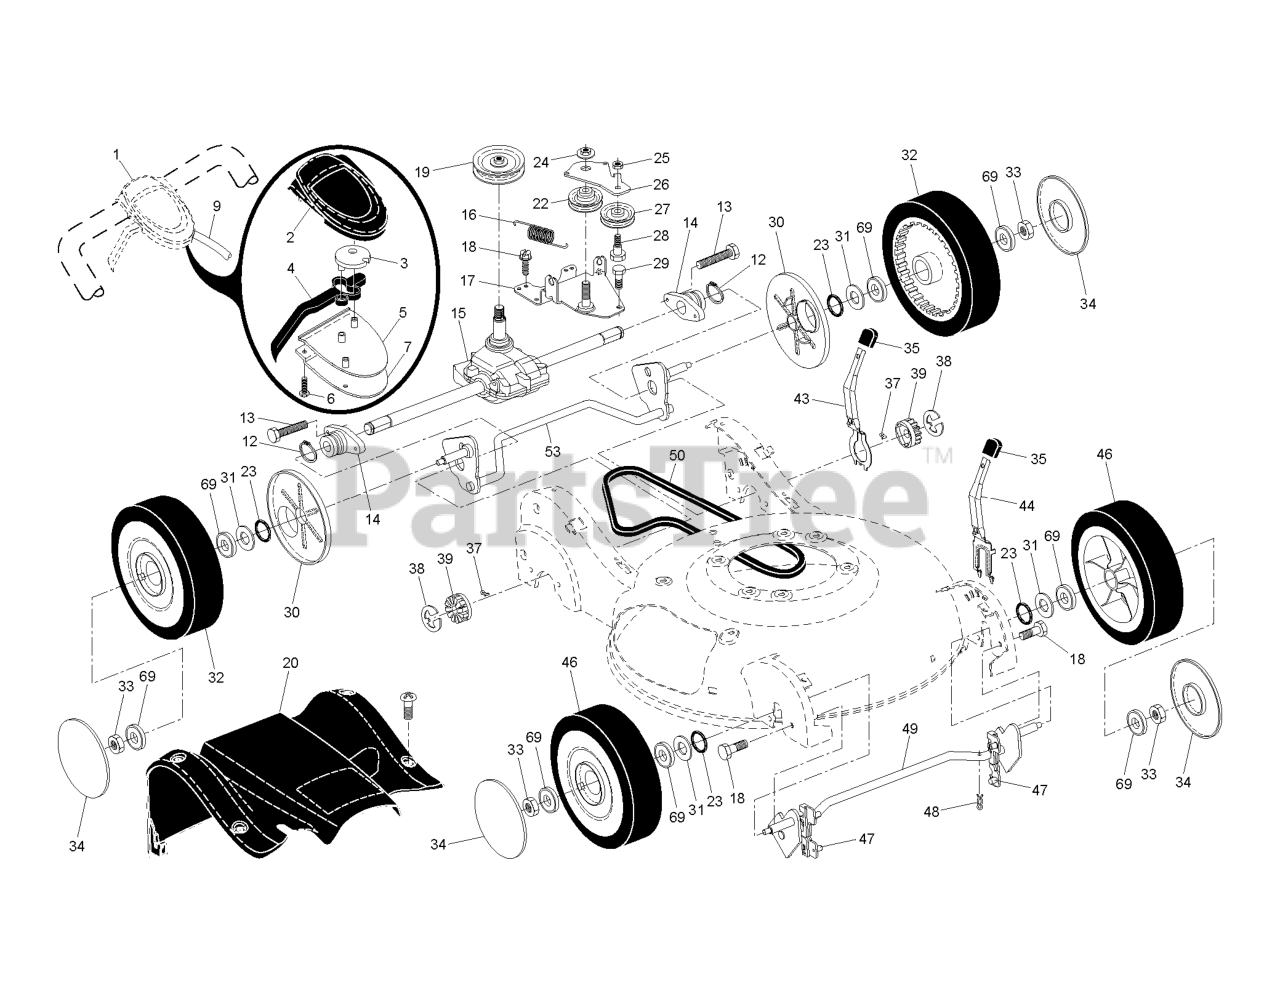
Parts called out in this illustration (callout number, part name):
1	Drive Control Assembly, Complete
2	COVER TOP AUTO WALK CONTROL
3	PULLEY.CAM.DRIVE.CONTROL.HV
4	LEVER.BLACK
5	COVER BOTTOM AUTO WLK CONTROL
6	SCREW, PHILLIPS HEAD 10 X 5/8
7	BRACKET.DRIVE.CONTROL.MOUNT.BL
9	ASM.CABLE.
12	RETAINING RING (2 2)(3 2)
13	SCREW.1/4-20X21/4.HEX.
14	BEARING / AXLE SUPPORT
15	TRANSMISSION.21.HV.RWGD.AW/EZ
17	BRACKET, GEAR CASE / DRIVE
19	RP PULLEY.DRIVE.EZ
20	COVER.DR.ASM.408006X418.CE
22	PULLEY.IDLER.V-BELT
23	O-RING..070X.487.NEOPRENE
24	NUT.HEX.FLANGE.3/8-16.LOCKNUT
25	NUT.CENTERLOCK.5/16-
26	ARM.IDLER.BZP
27	IDLER PULLEY
28	SHOULDER BOLT
29	SCREW 14-20 X 5/8
30	DUST COVER, WHEEL
31	WASHER.FLAT.1/2
32	WHEEL.9X2.25.LP.TIGER.BLACK
33	NUT.HEX.FLANGE.3/8-16.LO(3 2)
34	HUBCAP.WHEEL.5.SPOKE.SILVER
35	KNOB.SELECTOR.SPRING.BLACK(3 2
37	PAWL, DRIVE
38	E-RING 7/16 RE
39	PINION.14.TEETH.FGD
43	LEVER, SELECTOR, HEIGHT, REAR
44	LEVER, SELECTOR, HEIGHT, FRONT
46	WHEEL.9X2.25.LP.TIGER.BLK
47	BUSHING.FRONT.TORQUE.SHAFT
48	SPRING RETAINER
49	SHAFT FRONT
50	BELT, DRIVE
53	SHAFT.ASM.REAR.TORQUE.HV.BZP
69	BEARING.8".WHEEL
